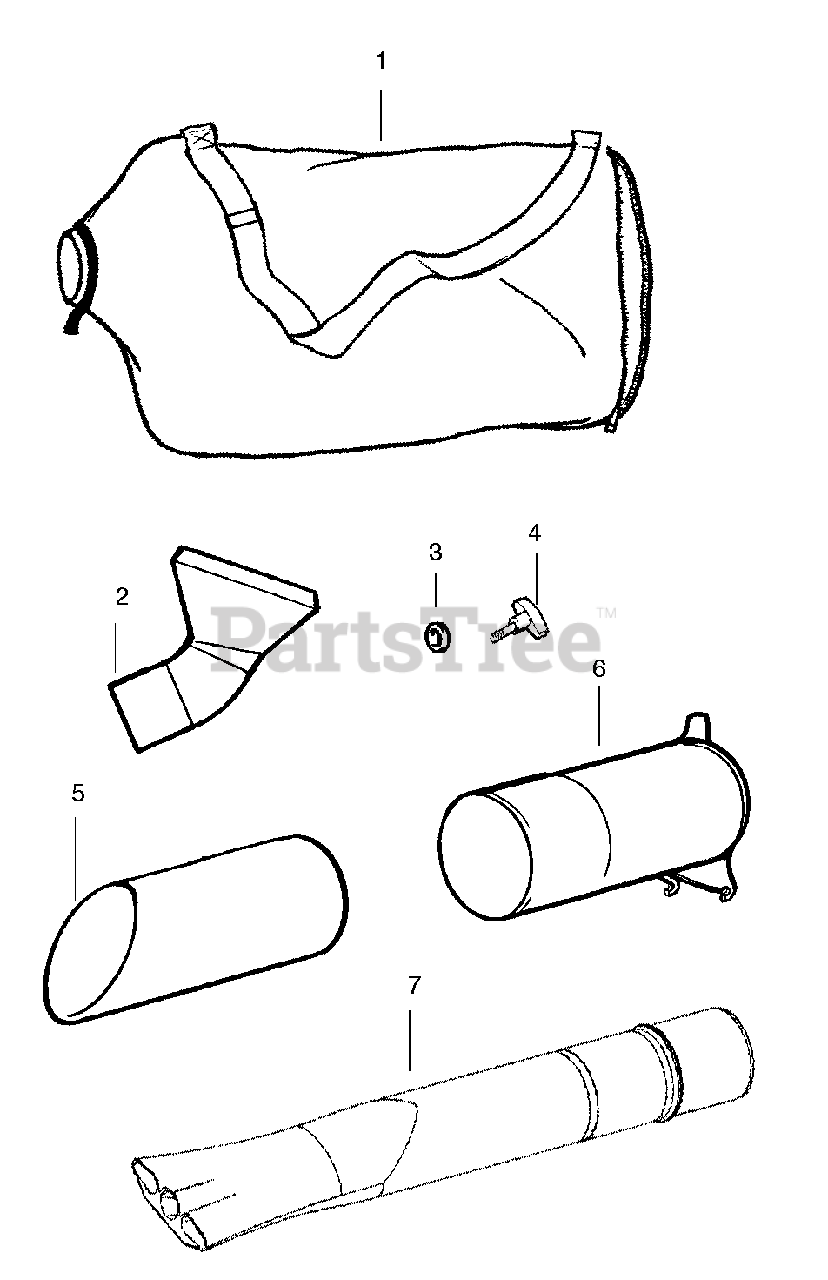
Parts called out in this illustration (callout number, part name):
1	Assy-Vac. Bag w/strap
2	Tube-Elbow Vac
3	Retainer-Vac Tube Knob
5	Tube-Lower Vac
6	Tube-Upper Vac
7	Tube-Blower
